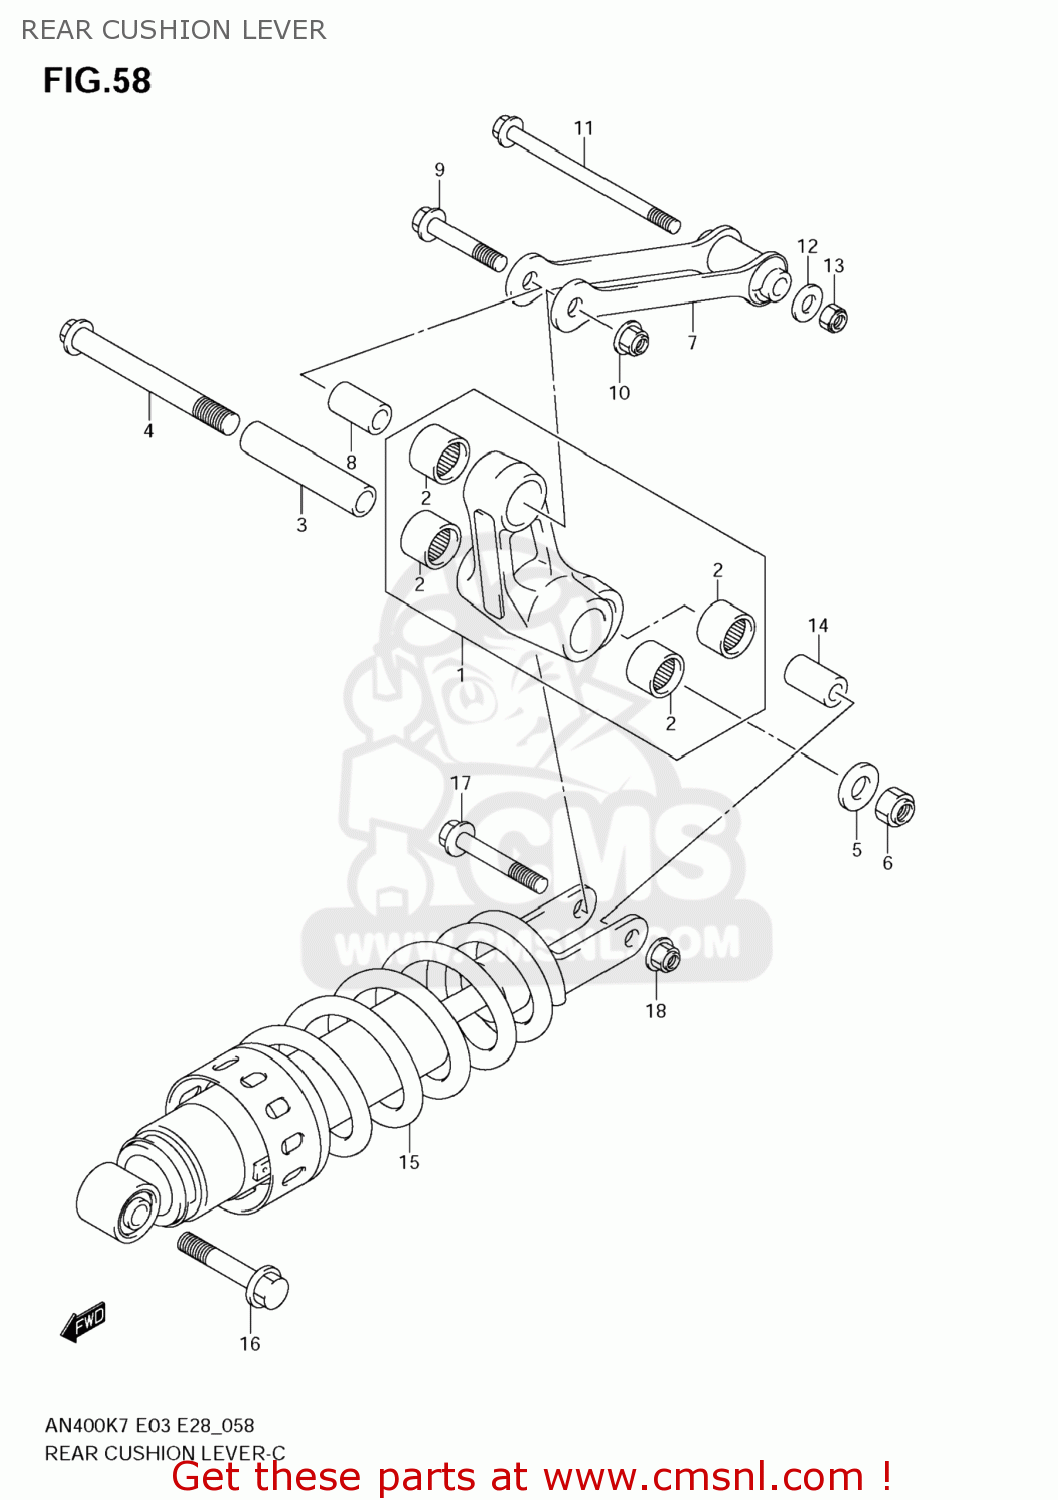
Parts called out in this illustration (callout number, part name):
1	LEVER SET,RR CUSHION
2	BEARING(17X24X26)
3	SPACER,RR CUSHION ROD
4	BOLT,RR CUSHION ROD
5	WASHER(12X25X4)
6	NUT
7	ROD,RR CUSHION LEVER
8	SPACER,RR CUSHION LEVER
9	BOLT(10X54)
10	NUT
11	BOLT(10X132)
12	WASHER(10.5X22X2.3)
13	NUT
14	SPACER,RR CUSHION LEVER
15	ABSORBER ASSY,RR SHOCK
16	BOLT(10X48)
17	BOLT(10X55)
18	NUT
